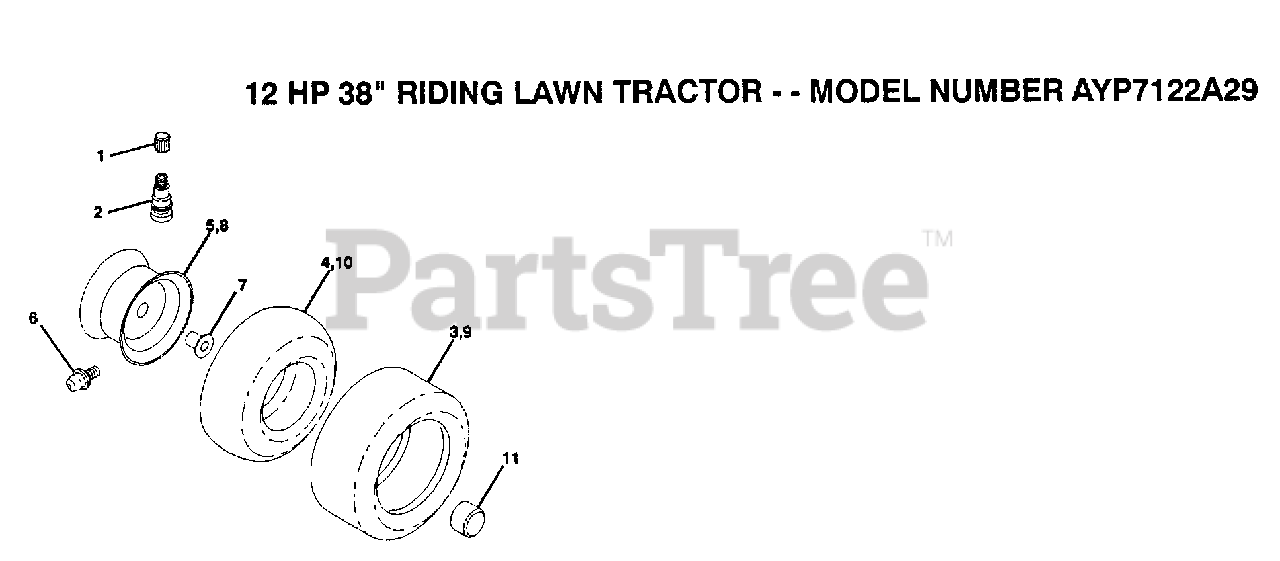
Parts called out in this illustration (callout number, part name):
1	VALVE CAP
2	VALVE STEM LT
4	TUBE.5.3/4.5/6
6	FITTING LT
7	"FLANGE, BEARING"
10	TUBE.18X9.5-8
11	HUB CAP
